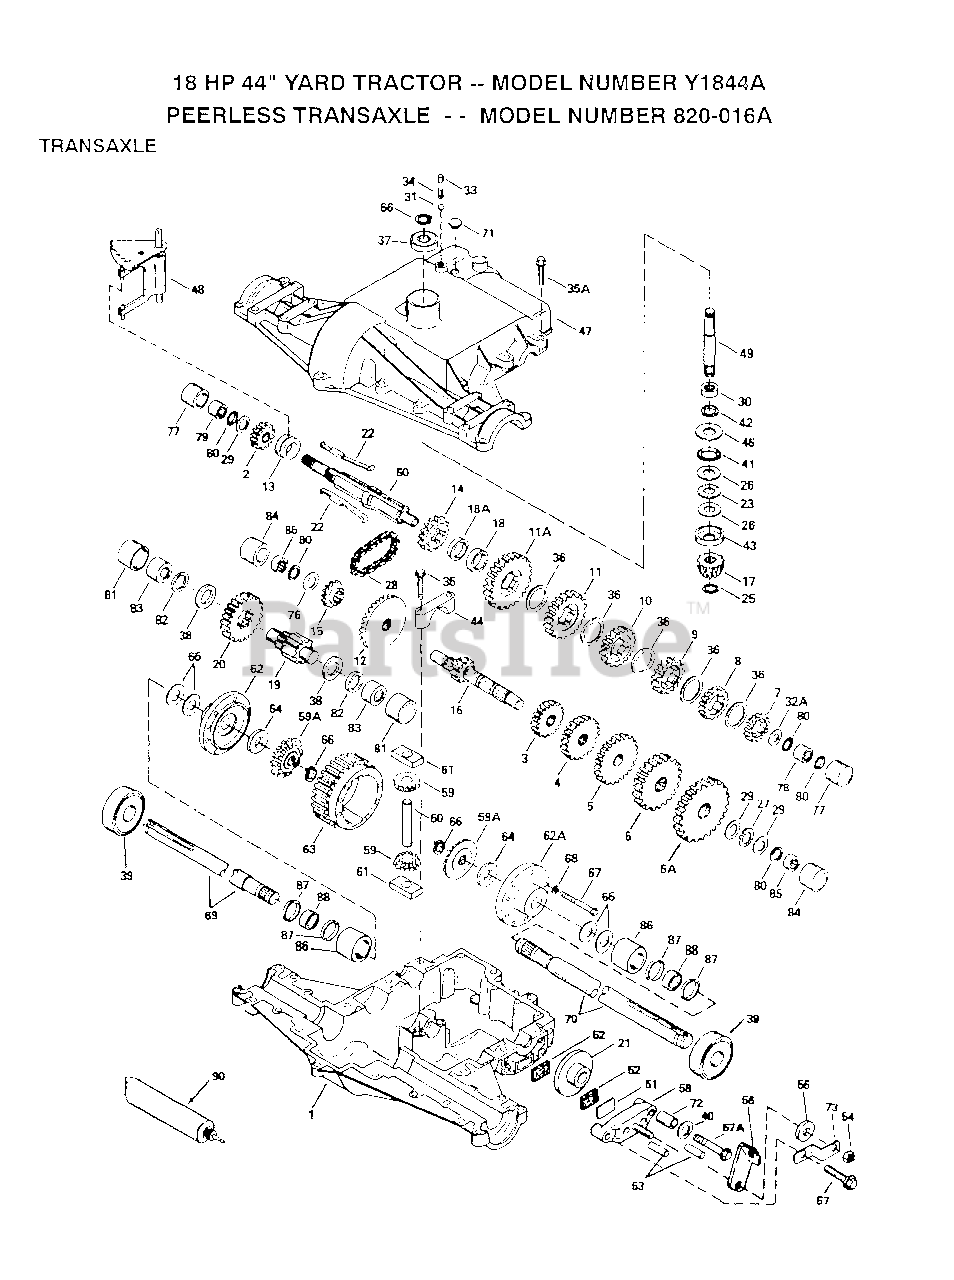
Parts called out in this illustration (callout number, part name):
1	CASE TRANSAXLE
2	GEAR, SPUR, 15T
3	GEAR, SPUR, 12 TEETH
4	GEAR, SPUR, 18 TEETH
5	GEAR, SPUR, 25T
6	GEAR, SPUR, 28T
6A	GEAR, SPUR, 31T
7	GEAR, SPUR, 19T
8	GEAR, SPUR, 22T
9	GEAR, SPUR, 22T
10	GEAR, SPUR, 32 TEETH
11	GEAR, SPUR, 37 TEETH
11A	GEAR, SPUR, 41T
12	GEAR BEVEL, 33T
13	COLLAR SHIFT
14	SPROCKET 18T (REV)
15	SPROCKET 9T
16	SHAFT COUNTER
17	BEVEL PINION, 13T
18	SPACER, .350/.340 THICK
18A	SPACER, .276/.268 THICK
19	SHAFT, OUTPUT, 9T
20	GEAR, OUTPUT, 35T
23	BEARING THRUST
25	RETAINING RING
26	WASHER THRUST
27	THRUST BEARING
28	CHAIN, ROLLER
29	WASHER THRUST
30	BEARING NEEDLE
31	BALL STEEL, 5/16" DIA.
33	SCREW, 3/8-16 X 3/8"
35	SCREW, 1/4-20 X 1-1/4
35A	SCREW HEX HD 5/16-18 X 1-1/4
36	WASHER THRUST
37	BEARING BALL
38	WASHER THRUST
39	BEARING BALL
40	WASHER FLAT
42	OIL SEAL 3/4
43	WASHER CUPPED
44	BEARING CAP
47	COVER TRANSAXLE
48	ROD AND FORK ASSY SHIFT
49	SHAFT INPUT
50	SHAFT BRAKE
51	PLATE BRAKE PAD
54	LOCKNUT 5/16-24
55	WASHER, FLAT
56	LEVER BRAKE
57	SCREW, 1/4-20 X 1-1/4
57A	SCREW FLNG HEX 1/4-20 X 2-1/4
58	HOLDER BRAKE PAD
59	PINION, 10T
61	BLOCK DRIVE
62	CARRIER DIFF THREADED HOLES
62A	CARRIER DIFF
63	GEAR, RING, 31T
65	WASHER THRUST
67	SCREW, 1/4-20 X 2-1/4
68	WASHER LOCK 1/4
69	AXLE, 12-5/16" LONG
70	AXLE, 16-3/16" LONG
71	PLUG, THRDED, 9/16-18
73	BRKT BRAKE LEVER
78	BEARING NEEDLE
79	BEARING NEEDLE
81	SLEEVE STEPPED
82	RING SQ CUT
83	BEARING NEEDLE CAPPED
84	SLEEVE STEPPED
85	BEARING NEEDLE CAPPED
86	SLEEVE STEPPED
87	RING SQ CUT
88	BEARING NEEDLE
90	GREASE BENTONITE, 32 OZ.
